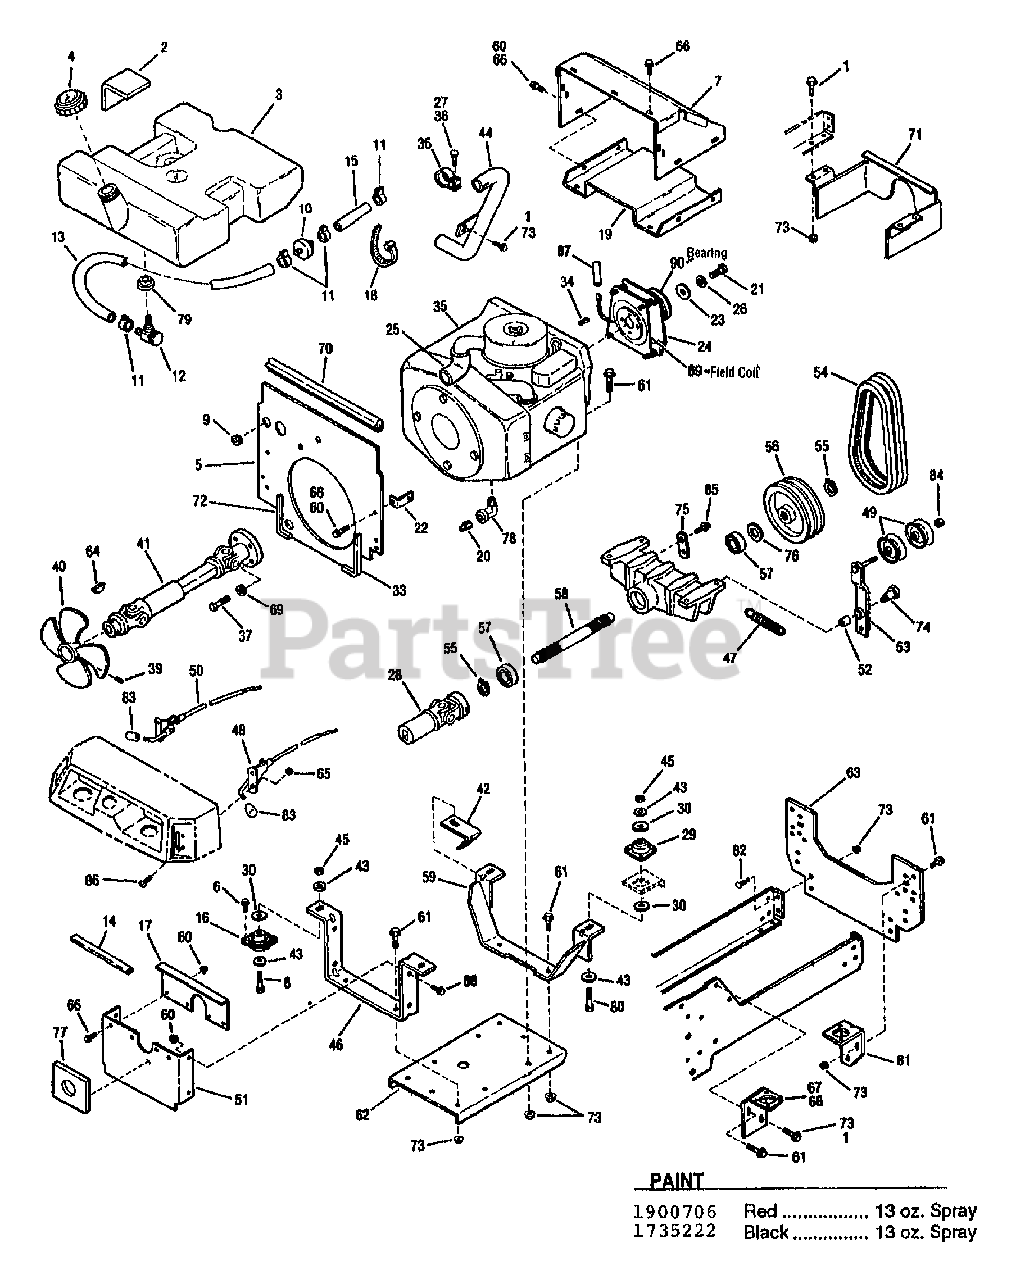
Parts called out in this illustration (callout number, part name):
2	PAD-FUEL TANK
3	ASSM-FUEL TANK
4	CAP-FUEL
5	SHIELD-HEAT
7	ASSM-HEAT SHIELD
8	SCR-HH 3/8-16X2.25 G5 ZP
9	BUSHING
10	FILTER-FUEL
11	CLAMP-HOSE
12	VALVE-SHUT OFF
13	FUEL LINE
14	GASKET-HEAT SHIELD
15	LINE-FUEL
17	SHIELD-GRASS UPPER
18	TIE-CABLE NYLON BLACK
19	SHIELD-HEAT
20	PLUG-PIPE
21	SCR-HH 7/16-20X1.25 G5ZP
22	BRKT-HEAT SHIELD
23	WASHER-1.7X.453X.25
24	CLUTCH {13062}
24	ELEC-CLUTCH/BRAKE {13060}
25	HOSE-AIR CLEANER
26	WASHER-LK .438 ZP
27	NUT-H/LK 5/16-18
28	JOINT-UNIVERSAL
28	KIT-CROSS REPAIR
29	MOUNT
30	WASHER
33	SEAL-RH
35	KOHLER ENGINE 20HP {KT200S 49540}{13062} {M20QS 49565}
35	KOHLER ENGINE 18HP {M18QS 24999}{13060}
36	CLAMP
37	SCR-HH 3/8-16X1.0 G5 ZP
38	SCR-CARR 5/16-18X1.25 G2ZP
39	SCR-SQ HD SET 5/16X3/4
40	FAN
41	SHAFT-DRIVE
42	BRKT-EXHAUST PIPE
43	WASHER-FLAT 1.25X.406X.179
44	PIPE-EXHAUST
45	NUT-LOCK 3/8-16
46	SUPPORT-REAR MOUNT
47	SPRING
48	THROTTLE-CONTROL
49	PULLEY-IDLER
50	CHOKE-CONTROL
51	SHIELD-GRASS LOWER
52	BUSHING
53	ARM-IDLER
54	BELT SET
55	RING-HEAVY EXT HD 1.0 ID
56	SHEAVE-PTO
57	BEARING-BALL
58	SHAFT-PTO
59	SUPPORT-FRONT MOUNT
60	NUT-HF/LK 1/4-20 ZP
61	SCR-HFLK 3/8-16X1.00 ZP
62	MOUNT-ENGINE
63	PLATE-FRONT
64	KEY-WOODRUFF
65	NUT W/LKWASHER 10-24 ZP
66	SCR-HFLK 1/4-20X.50 ZP
67	ASSM-HANGER RH
68	ASSM-HANGER LH
69	WASHER-LK .375 @ DEPL
71	GUARD-PTO
72	SEAL-LH
73	NUT-HFLK 3/8-16 ZP
75	ANCHOR-SPRING
76	WASHER-THRUST
78	ELBOW-45 DEGREES
79	BUSHING-RUBBER
80	SCR-HHC 3/8-16X3.25
81	SUPPORT-ENGINE
82	SCR-CARR 3/8-16X.75 G5 ZP
83	KNOB
84	NUT-HEX/JAM 3/8-16 ZP
85	SCR-HFLK 5/16-18X.75 ZP
87	INSULATOR
90	BEARING
